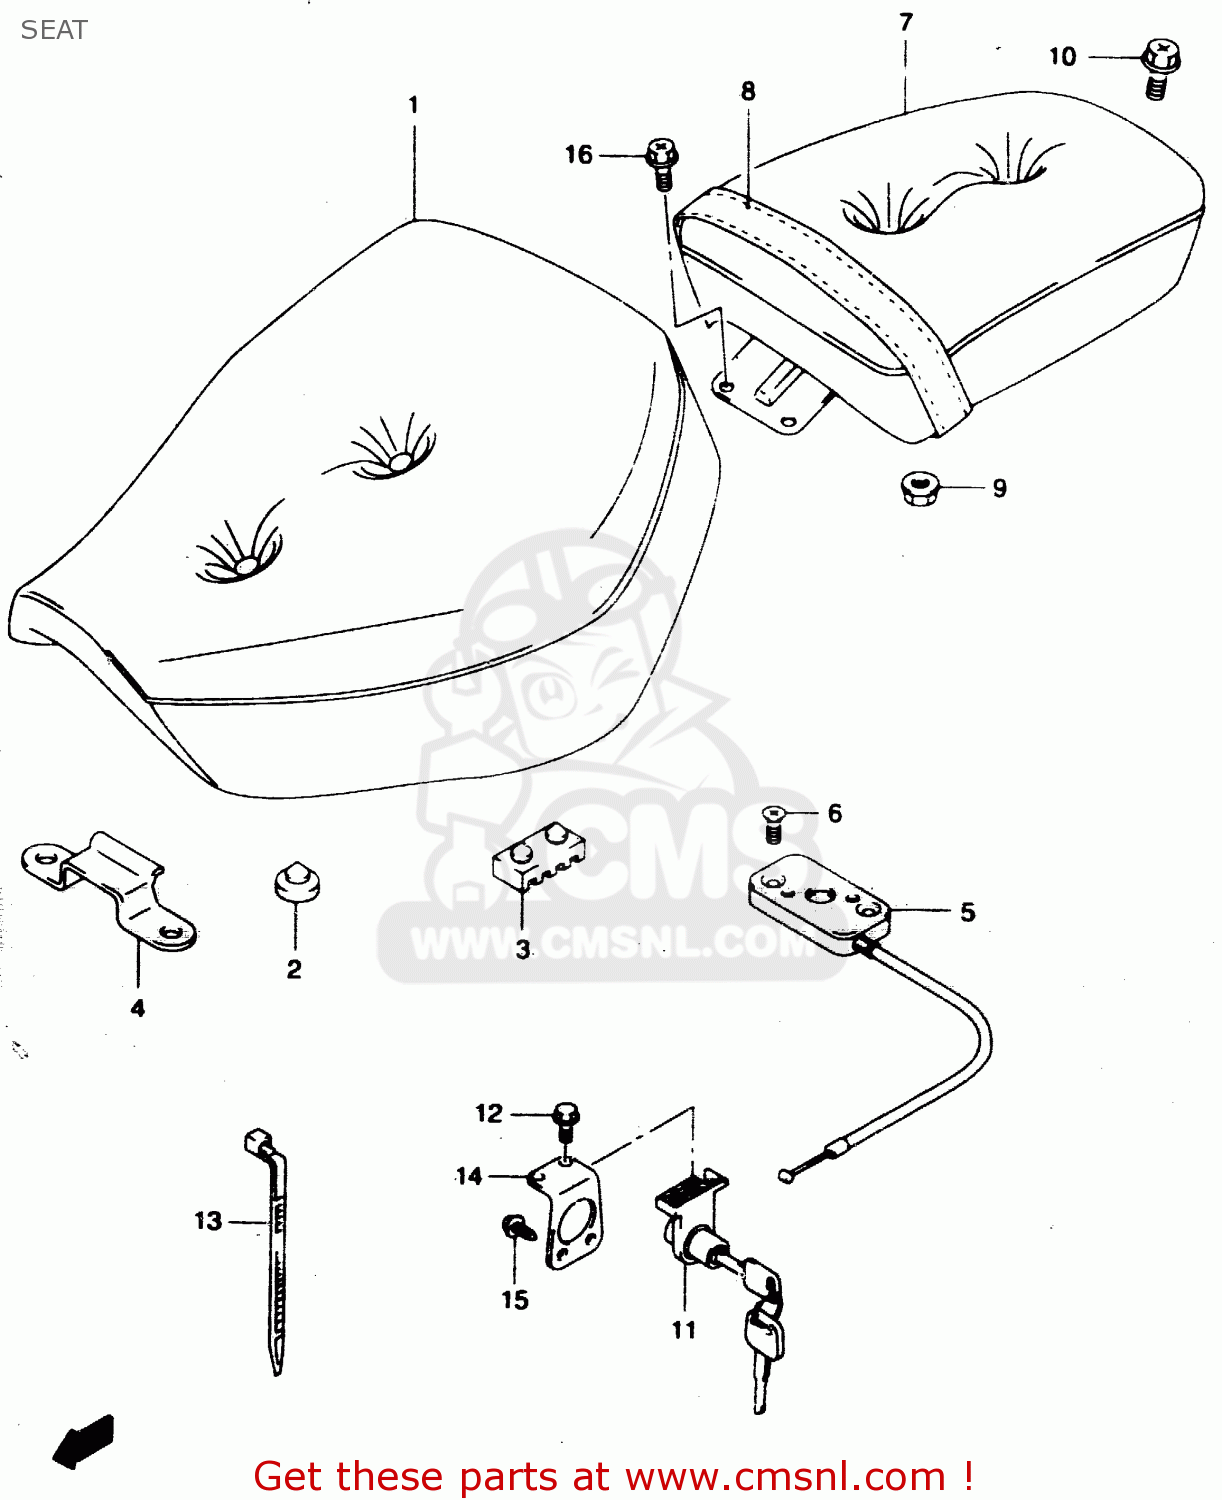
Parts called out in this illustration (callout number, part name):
1	SEAT ASSEMBLY
2	CUSHION,SEAT
3	CUSHION,SEAT(40X20X15)
4	PLATE,FR SEAT HOOK
5	BRACKET,SEAT SUPPORT
6	SCREW
7	SEAT ASSEMBLY,PILLION
8	BAND,SEAT(BLACK)
9	NUT
10	BOLT(8X16)
11	LOCK SET,SEAT
12	BOLT
13	CLAMP(L:220)
14	BRACKET,SEAT LOCK
15	SCREW
16	BOLT(6X12)
